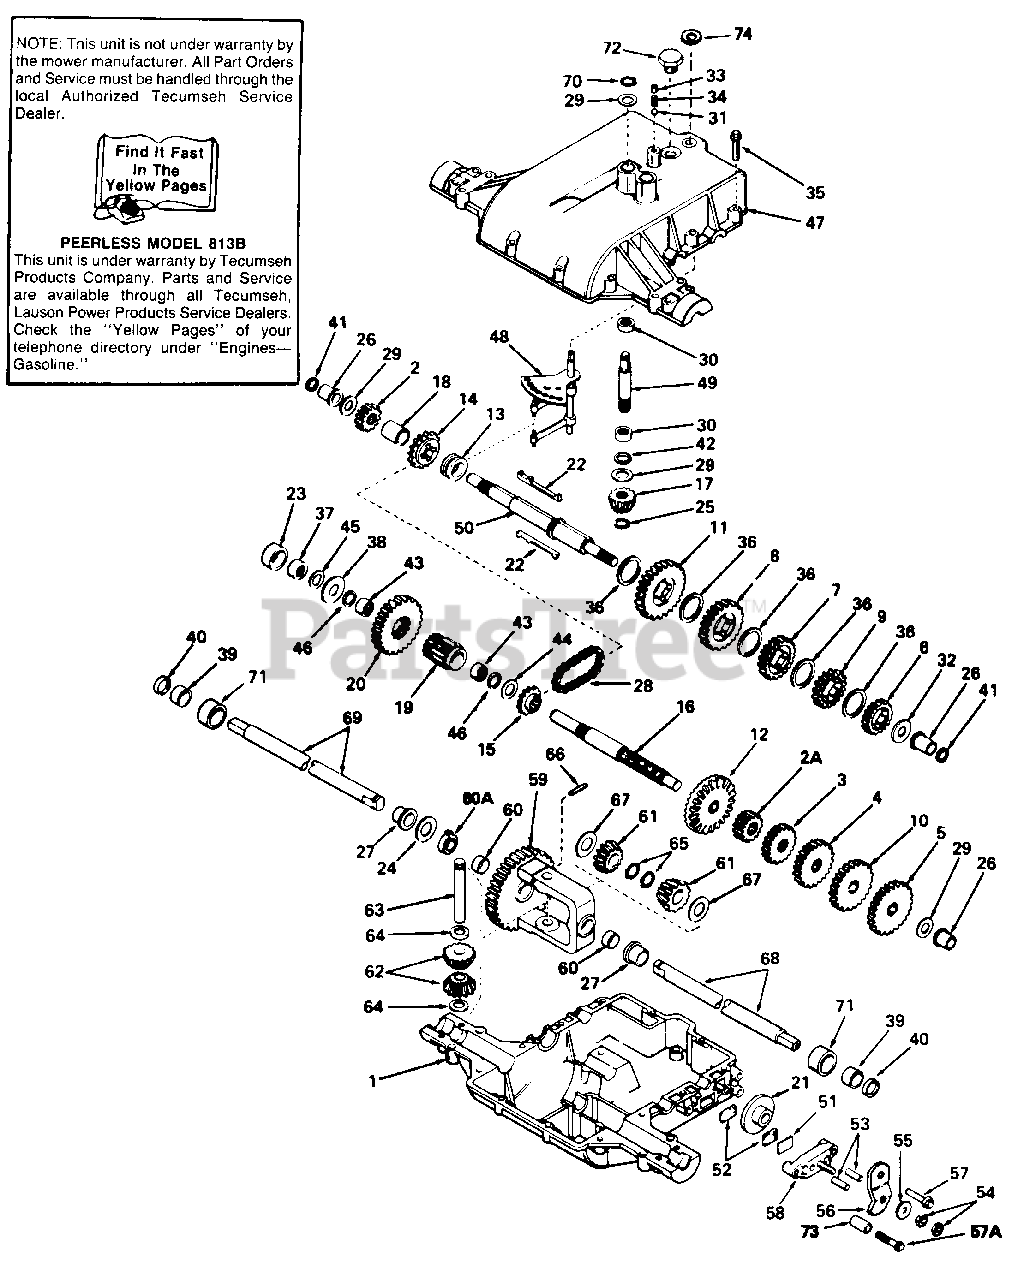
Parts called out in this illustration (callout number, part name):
1	Case: Transaxle
2	Gear: Spur (15 Teeth)
2A	Gear: Spur (12 Teeth)
3	Gear: Spur (15 Teeth)
4	Gear: Spur (20 Teeth)
5	Gear: Spur (30 Teeth)
6	Gear: Spur (20 Teeth)
7	Gear: Spur (30 Teeth)
8	Gear: Spur (35 Teeth)
9	Gear: Spur (25 Teeth)
10	Gear: Spur (25 Teeth)
11	Gear. Spur (37 Teeth)
12	Gear: Bevel (42 Teeth)
13	Collar: Shift
14	Sprocket (18 Teeth)
15	Sprocket (9 Teeth)
16	Shaft: Counter
17	Bevel Pinion: Input
18	Spacer
19	Pinion: Output
20	Gear: Output
21	Disc: Brake
22	Key
23	Spacer
24	Washer
25	Ring: Retaining
26	Bushing: Flanged
27	Bushing: Flanged
28	Chain: Roller (No. 41 Chain: 24 Links)
29	Washer: Thrust
30	Bearing: Needle
31	Ball: Steel
32	Washer: Thrust
33	Screw: Set: 3/8-16 x 3/8
34	Spring
35	Screw: Hex Hd. Thread Forming: 1/4-20 x 1-1/4
36	Washer: Thrust
37	Bearing: Needle
38	Washer: Flat
39	Bearing: Needle
40	Seal: Oil
41	Ring: Square Cut
42	Ring: Square Cut
43	Bearing: Needle
44	Washer: Flat
45	Ring: Square Cut
46	Ring: Square Cut
47	Cover: Transaxle
48	Rod and Fork Ass'y.: Shift
49	Shaft: Input
50	Shaft: Brake
51	Plate: Brake Pad
52	Pad: Brake
53	Pin: Dowel
54	Lock Nut: 5/16-24
55	Washer: Flat
56	Lever: Brake
57	Screw: Hex Hd. Thread Forming: 1/4-20 x 1-1/4
57A	Screw: Hex Hd. Thread Forming: 1/4-20 x 2-1/4
58	Holder: Brake Pad
59	Gear Ass'y.: Differential
60	Bushing
60A	Bushing
61	Gear: Bevel
62	Pinion: Bevel
63	Pin Drive
64	Washer: Thrust
65	Ring: Retaining
66	Pin: Roll
67	Washer: Thrust
68	Axle (14-7/8" Long)
69	Axle (13" Long)
70	Ring: Retaining
71	Spacer
73	Spacer
74	Washer
